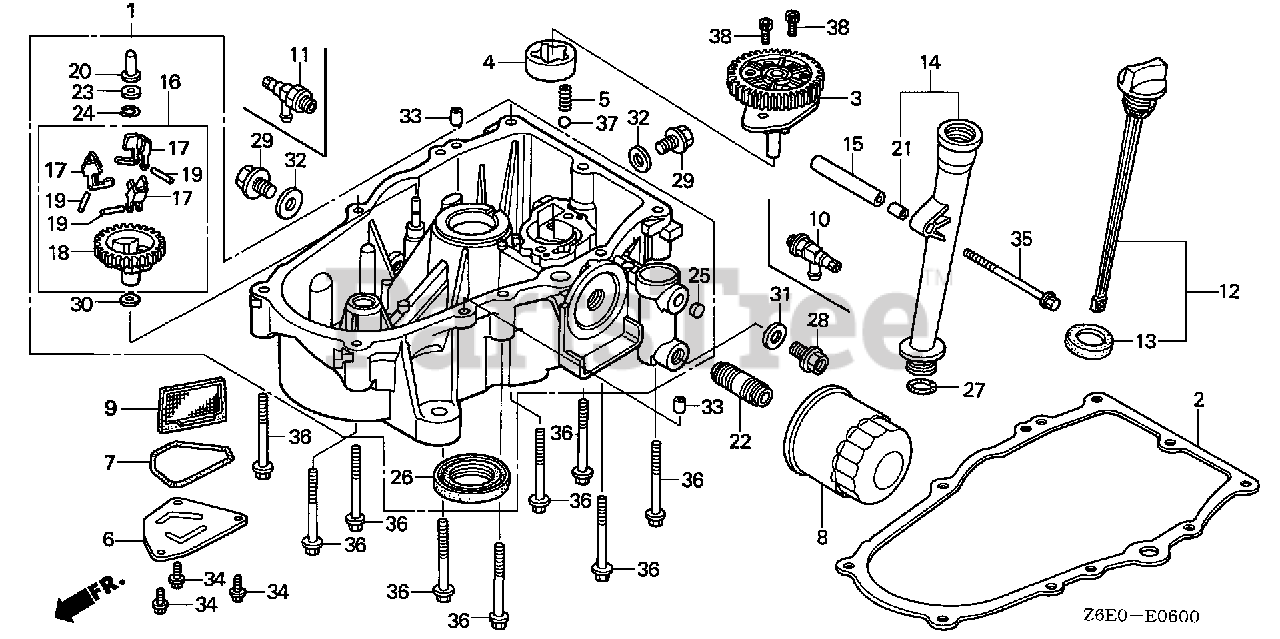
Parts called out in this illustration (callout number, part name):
1	PAN ASSY., OIL
2	GASKET, CASE COVER
3	COVER ASSY., OIL PUMP (THREE BOLTS)
4	ROTOR, OIL PUMP (OUTER)
5	SPRING, RELIEF VALVE
6	PLATE, OIL FILTER
7	O-RING, OIL PLATE
8	FILTER, OIL (FILTECH TOYO ROKI) (SOLD INDIVIDUALLY)
8	FILTER, OIL (TOYO ROKI) (SOLD INDIVIDUALLY)
9	SCREEN, OIL FILTER
10	VALVE, DRAIN (14X1.5)
11	VALVE, OIL SHUT-OFF
12	CAP ASSY., OIL FILLER
13	GASKET, OIL FILLER CAP
14	EXTENSION, OIL FILLER
15	COLLAR, FILLER SETTING
16	GOVERNOR ASSY.
17	WEIGHT, GOVERNOR
18	HOLDER, GOVERNOR WEIGHT
19	PIN, GOVERNOR WEIGHT
20	SLIDER, GOVERNOR
21	COLLAR, EXTENSION
22	HOLDER, OIL FILTER
23	WASHER (6X16)
24	CLIP, GOVERNOR HOLDER
25	PLUG, SEALING (10MM)
26	OIL SEAL (38X58X9)
27	O-RING (22.1X2.2)
28	BOLT, DRAIN PLUG (14MM)
29	BOLT, DRAIN PLUG (20MM)
30	WASHER, PLAIN (6MM)
31	WASHER, DRAIN PLUG (14MM)
32	WASHER, DRAIN PLUG (20MM)
33	PIN, DOWEL (8X14)
34	BOLT, FLANGE (6X14)
35	BOLT, FLANGE (6X100)
36	BOLT, FLANGE (8X50)
37	BALL, STEEL (#12) (3/8)
38	BOLT, SOCKET (6X16)
